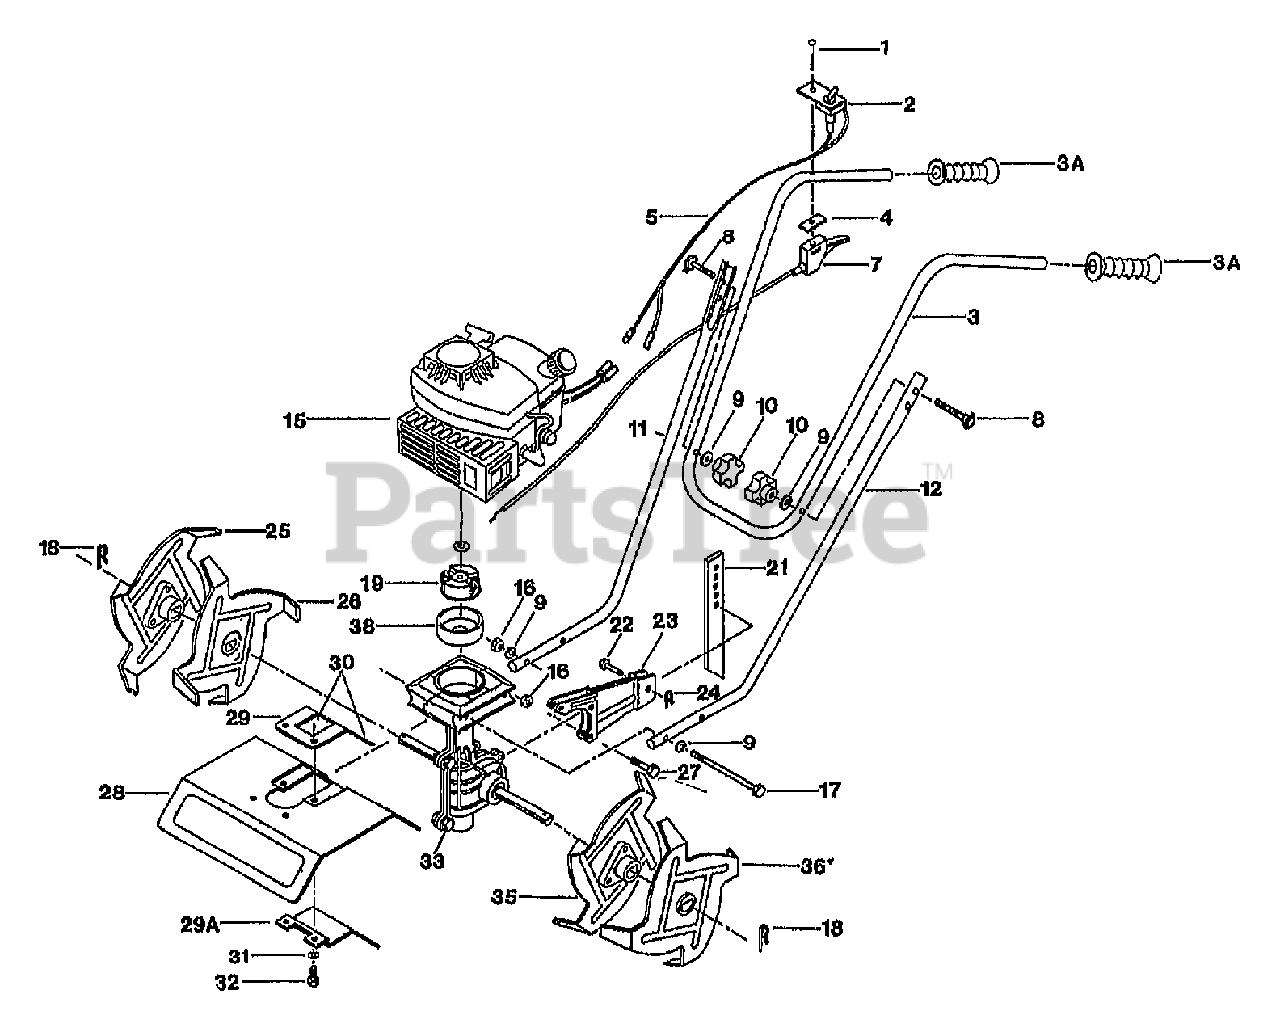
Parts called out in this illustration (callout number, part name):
1	SCR-PHD PHIL #10-16X1.5
2	SWITCH-IGN. 96506
3	ASSM-UPR HANDLEBAR
3A	GRIP-HANDLEBAR 97030
4	PAD-ISOLATOR TRIGGER
5	HARNESS-WIRE ASSM
6	REF. NO. NOT USED
7	ASSM-THROTTLE CONTROL
8	SCR-CURVED HD 5/16-18X2.0
9	WASHER-FLAT 5/16 SAE
11	H/BAR-LWR RIGHT PNT
12	H/BAR-LWR LEFT PNT
15	ENGINE, TECUMSEH TEC-200-2106
16	NUT-LK 1/4-20
17	SCR-HH 1/4-20X5
18	PIN-HITCH .149DIA
19	ASSM-CLUTCH ROTOR W/WASHER
21	DRAGSTAKE-PNT
22	PIN-CLEVIS
23	BRKT-WHEEL ASSM PNT
24	CLIP-HAIRPIN .07 DIA
25	ASSM-TINE OUTER RH
26	ASSM-TINE INNER RH
27	SCR 1/4-20X1.125 (DRAG STAKE TO TRANSMISSION)
28	SHIELD-TINE W/DECALS
29	HOOD-FILL PIECE MINI PNT
29A	SHIELD-ROCK PNT
30	SCR M10-32X.375 SELF-TAPPING (FOR REAR TIME COVER PLATE)
31	WASHER-LK .25
32	SCR-HH 1/4-20X2.0 G5
33	SCR-HH 1/4-20 X .875 G5
35	ASSM-TINE INNER LH
36	ASSM-TINE OUTER LH
38	ASSM-CLUTCH & DRUM
